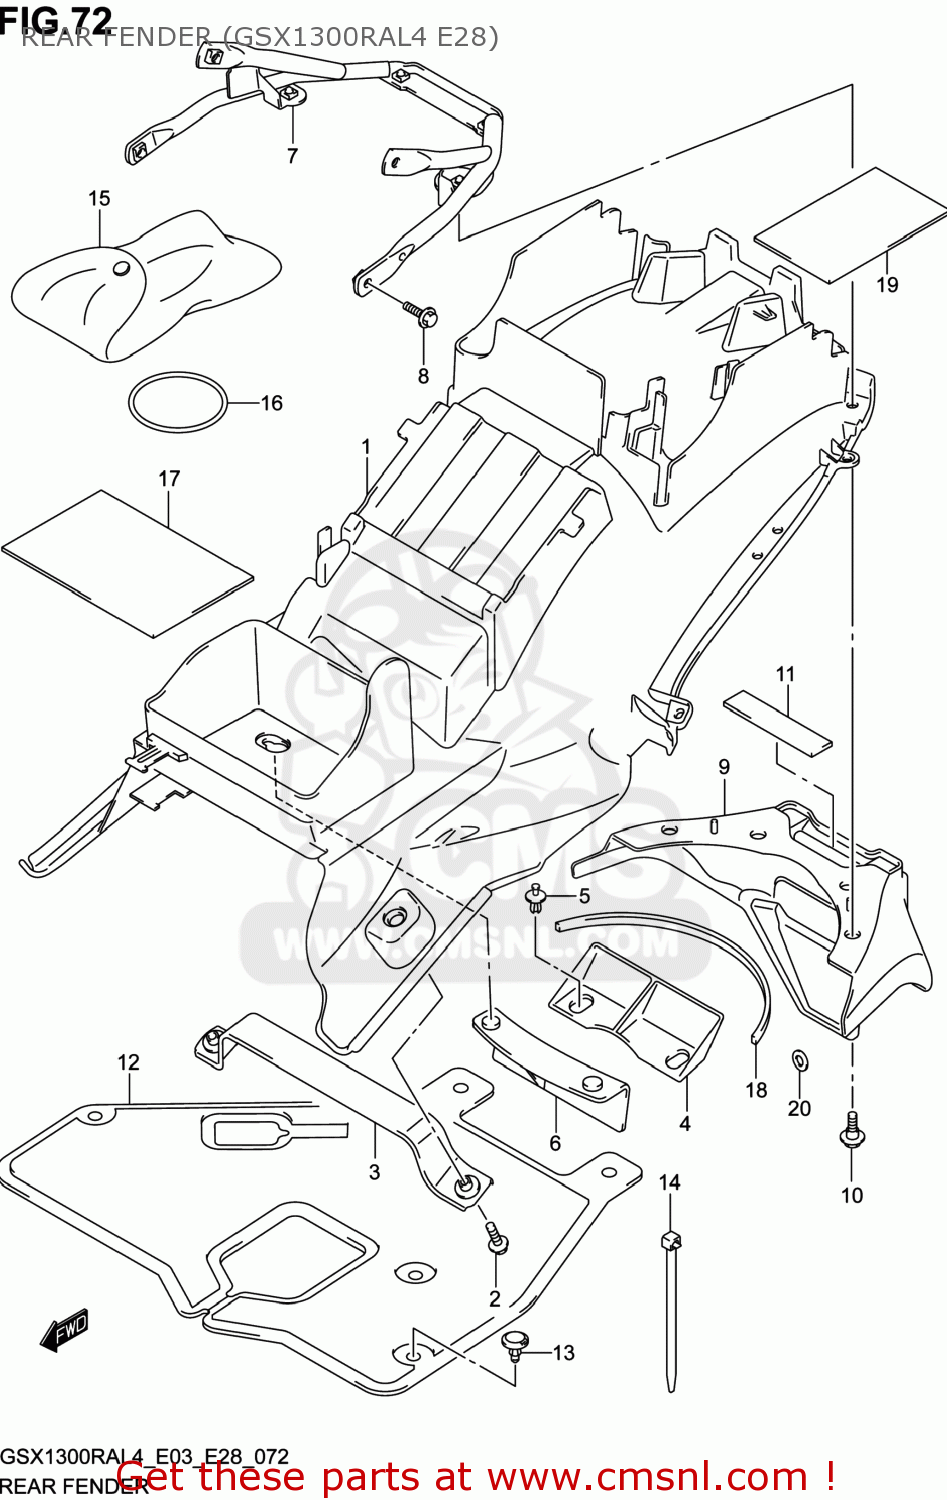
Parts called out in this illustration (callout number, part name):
1	FENDER,RR FR
2	BOLT
3	BRACKET,RR FENDER FR
4	MUDGUARD,RR FENDER
5	CLIP
6	MUDGUARD,RR FENDER FR UPR
7	BRACKET,RR FENDER
8	BOLT
9	FENDER,RR RR
10	BOLT(6X16)
11	PROTECTOR(20X90)X4
12	SHIELD,INNER
13	CLIP
14	CLAMP(L:95)
15	TOOL ASSY
16	O RING(D:3.5,ID:56.5)
17	CUSHION,RR FENDER FR
18	CUSHION,RR FENDER RR
19	CUSHION,TOOL BAG
20	WASHER
